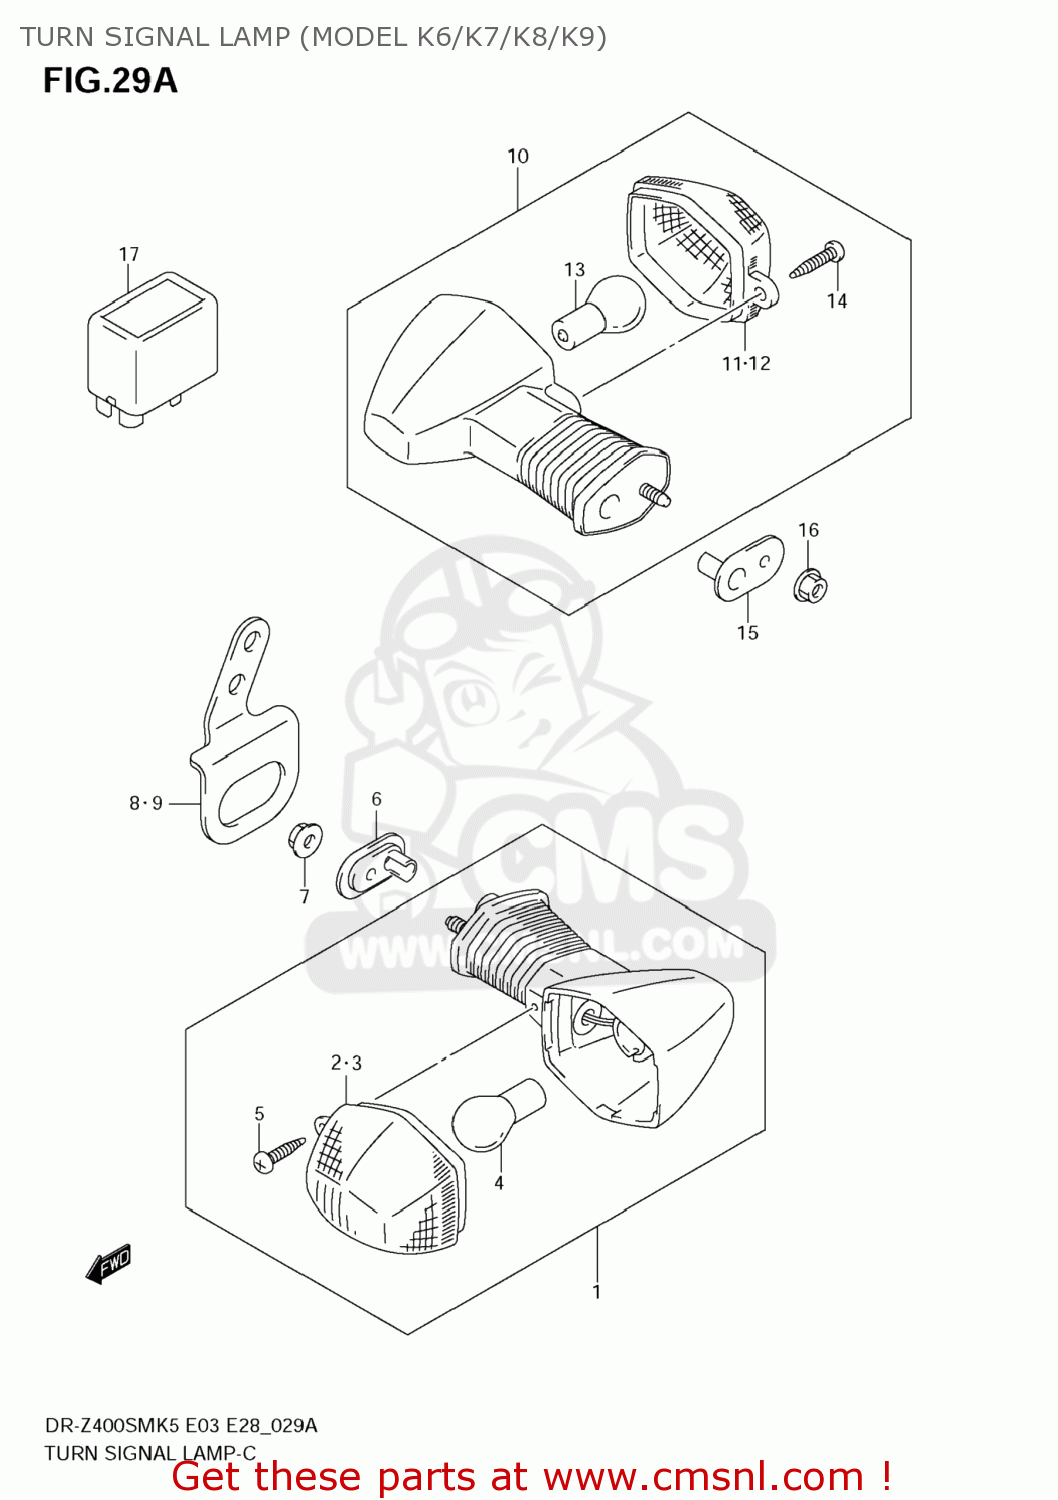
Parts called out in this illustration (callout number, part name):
1	LAMP ASSY,FR TURN SIGNAL,R
2	LENS
3	LENS
4	BULB(12V21W,AMBER)
5	SCREW
6	PLATE,TURNSIGNAL LAMP
7	NUT
8	BRACKET,FR TURNSIGNAL,R
9	BRACKET,FR TURNSIGNAL,L
10	LAMP ASSY,RR TURNSIGNAL,R
11	LENS
12	LENS
13	BULB(12V21W,AMBER)
14	SCREW
15	PLATE,TURNSIGNAL LAMP
16	NUT
17	RELAY ASSY,TURNSIGNAL LAMP
